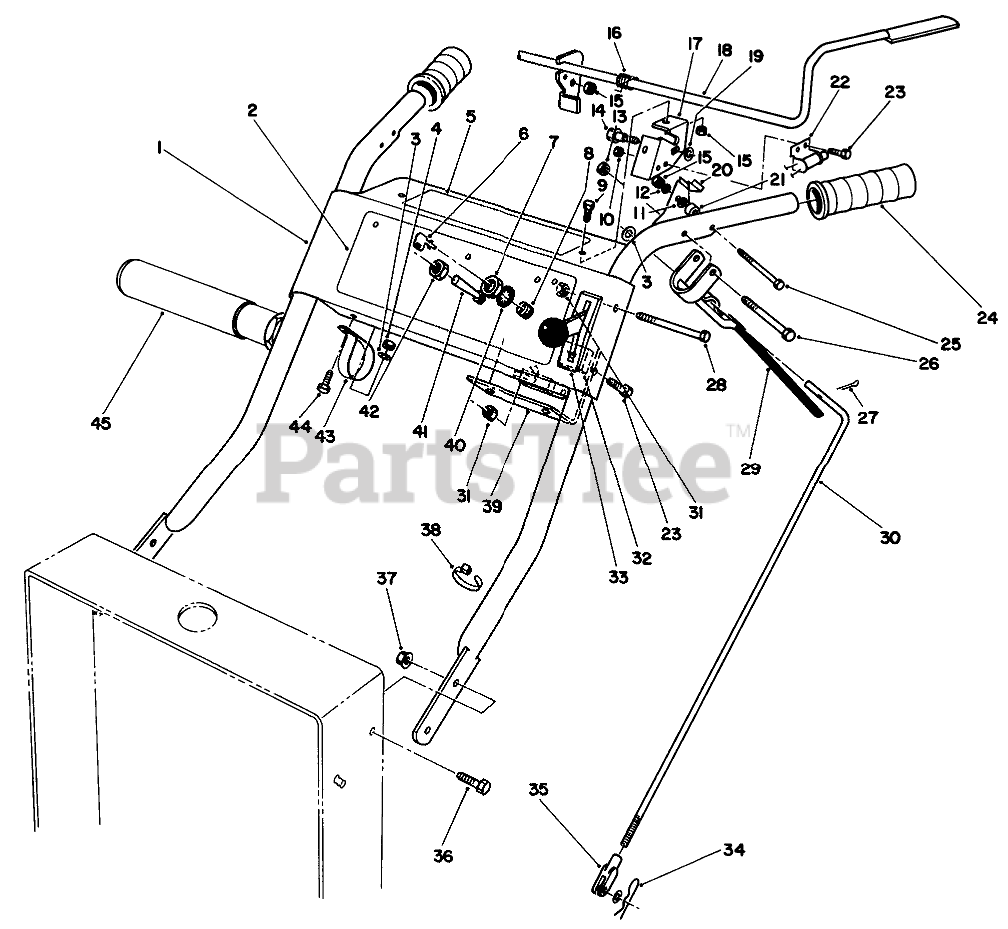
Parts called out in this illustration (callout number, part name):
1	HANDLE WA R
2	DECAL- CONTROL PANEL
3	WASHER-FLAT
4	NUT-LOCK, NI
5	DECAL - INSTRUCTION
6	KEY-IGNITION
7	NUT-HH
8	Switch (Incl. Ref. #7 & 40)
9	SCREW-HH
10	NUT-KEPS
11	WASHER
12	WASHER-BELLEVILLE
13	NUT-LOCK, NI
14	BOLT-SHOULDER
15	NUT-LOCK, NI
16	TORSION SPRING
17	INTERLOCK MTG BRKT B
18	INTERLOCK BAIL WA B
19	WASHER-LOCK/SP
20	LH NEUTRAL BRACKET
21	SPACER
22	DECK INTERLOCK SWITCH
23	SCREW-HWH
24	HANDLE GRIP
25	SCREW-HH
26	SCREW-HH
27	PIN-COTTER
28	SCREW-SHH
29	LIFT BAIL WA
30	CONTROL ROD
31	NUT-LOCK, NI
32	RECTIFIER-BRIDGE
33	CONTROL-THROTTLE
34	PIN-COTTER
35	CLEVIS-ADJ
36	SCREW-HHF
37	NUT-HF
38	TIE-CABLE
39	SWITCH COVER R
40	WASHER-TOOTH, INTERNAL
41	Switch-Clutch (Incl. Ref.# 42)
42	NUT
43	CLAMP-R
45	TUBE-MANUAL
